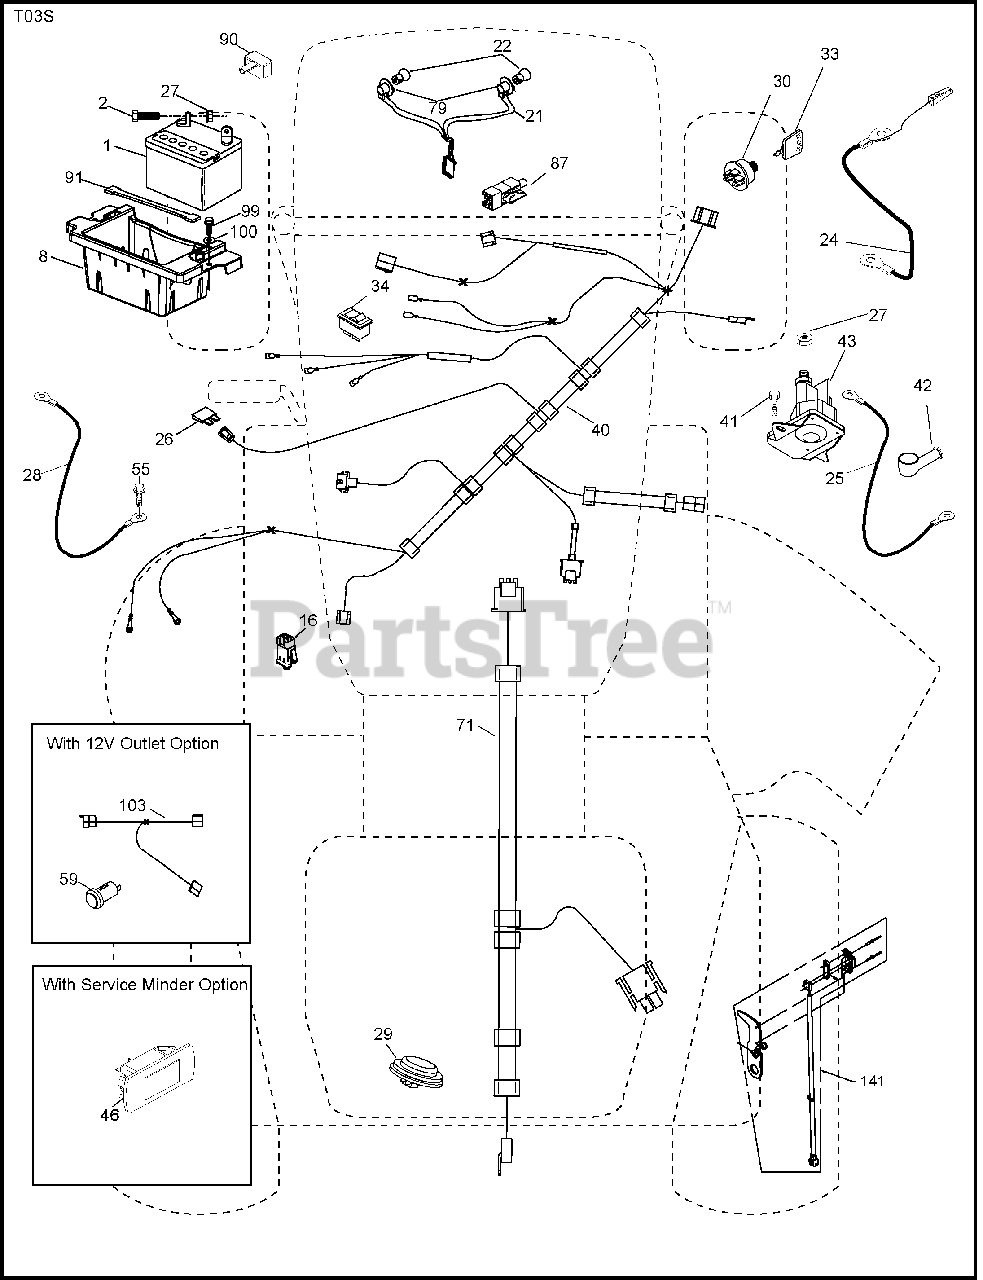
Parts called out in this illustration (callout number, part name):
1	Battery
2	Bolt Hex Head 1/4-20 x 3/4
8	Box Battery
16	Switch Interlock Push-In
21	Harness Socket Light w/4152J
22	Bulb Light
24	Cable Btry.
25	Cable Starter
26	Fuse
27	Nut Keps Hex 1/4-20 unc
28	Cable, Ground
29	Switch, Seat
30	Switch, Ign
33	Key, Ignition
34	Switch Light / Reset
40	Harness Ign. Dash
41	Screw Thd Cut 1/4-20 x 1/2
42	Cover, Terminal
43	Solenoid
55	Screw Thdrol 5/16-18 x 3/4 TYTT
71	Harness Chassis
79	Socket Asm Bulb Twistlock
87	Switch Interlock Clutch Cable
90	Cover Terminal
91	Strap Battery
99	Screw 1/4 - 20 x 3/4
100	Washer 9/32 x 7/8 x 16 Ga.
